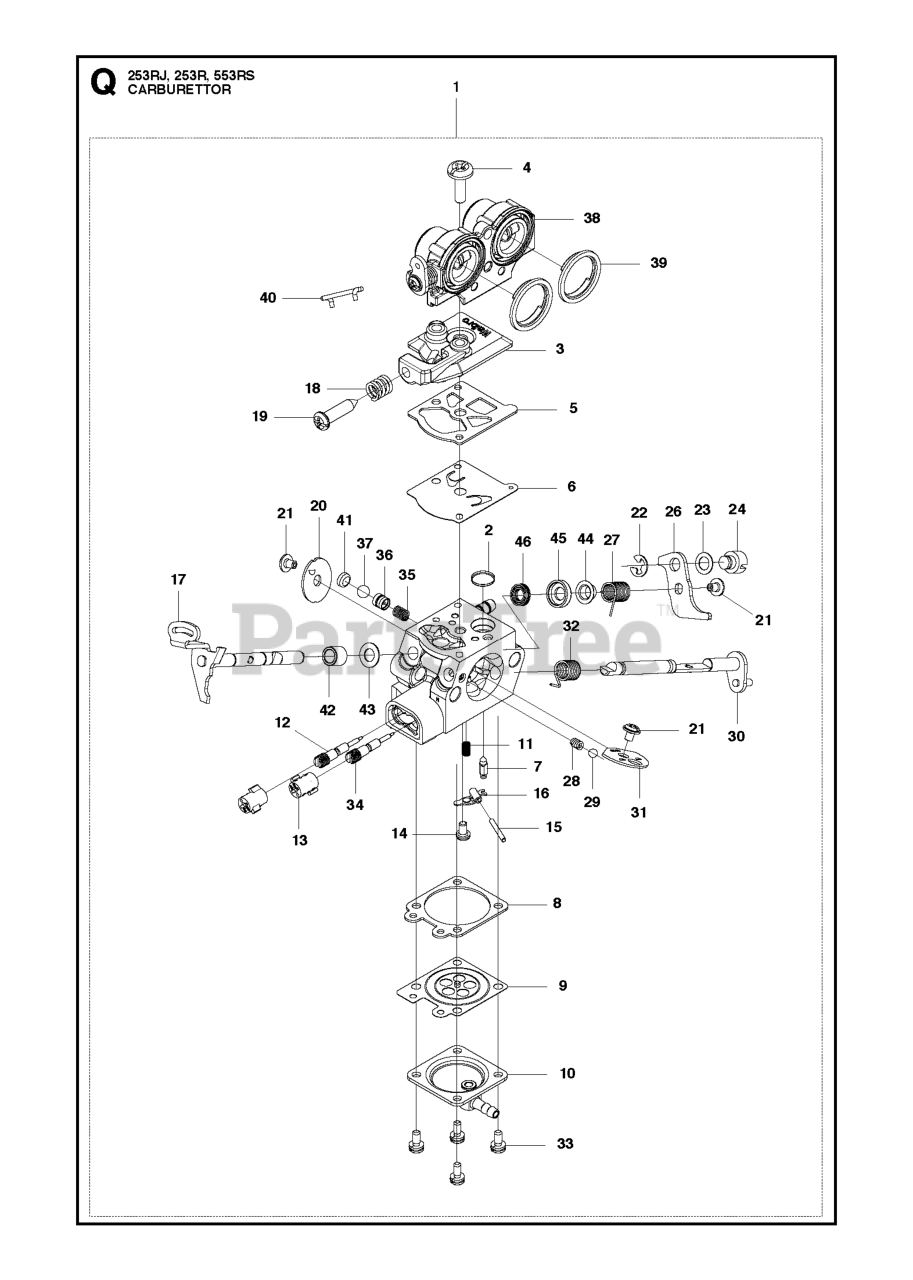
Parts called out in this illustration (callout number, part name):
2	SCREEN
7	VALVE INLET
26	LEVER, THROTTLE
30	SHAFT, CHOKE
31	ACCELATOR
33	SCREW ASSY
36	PISTON
37	BALL
